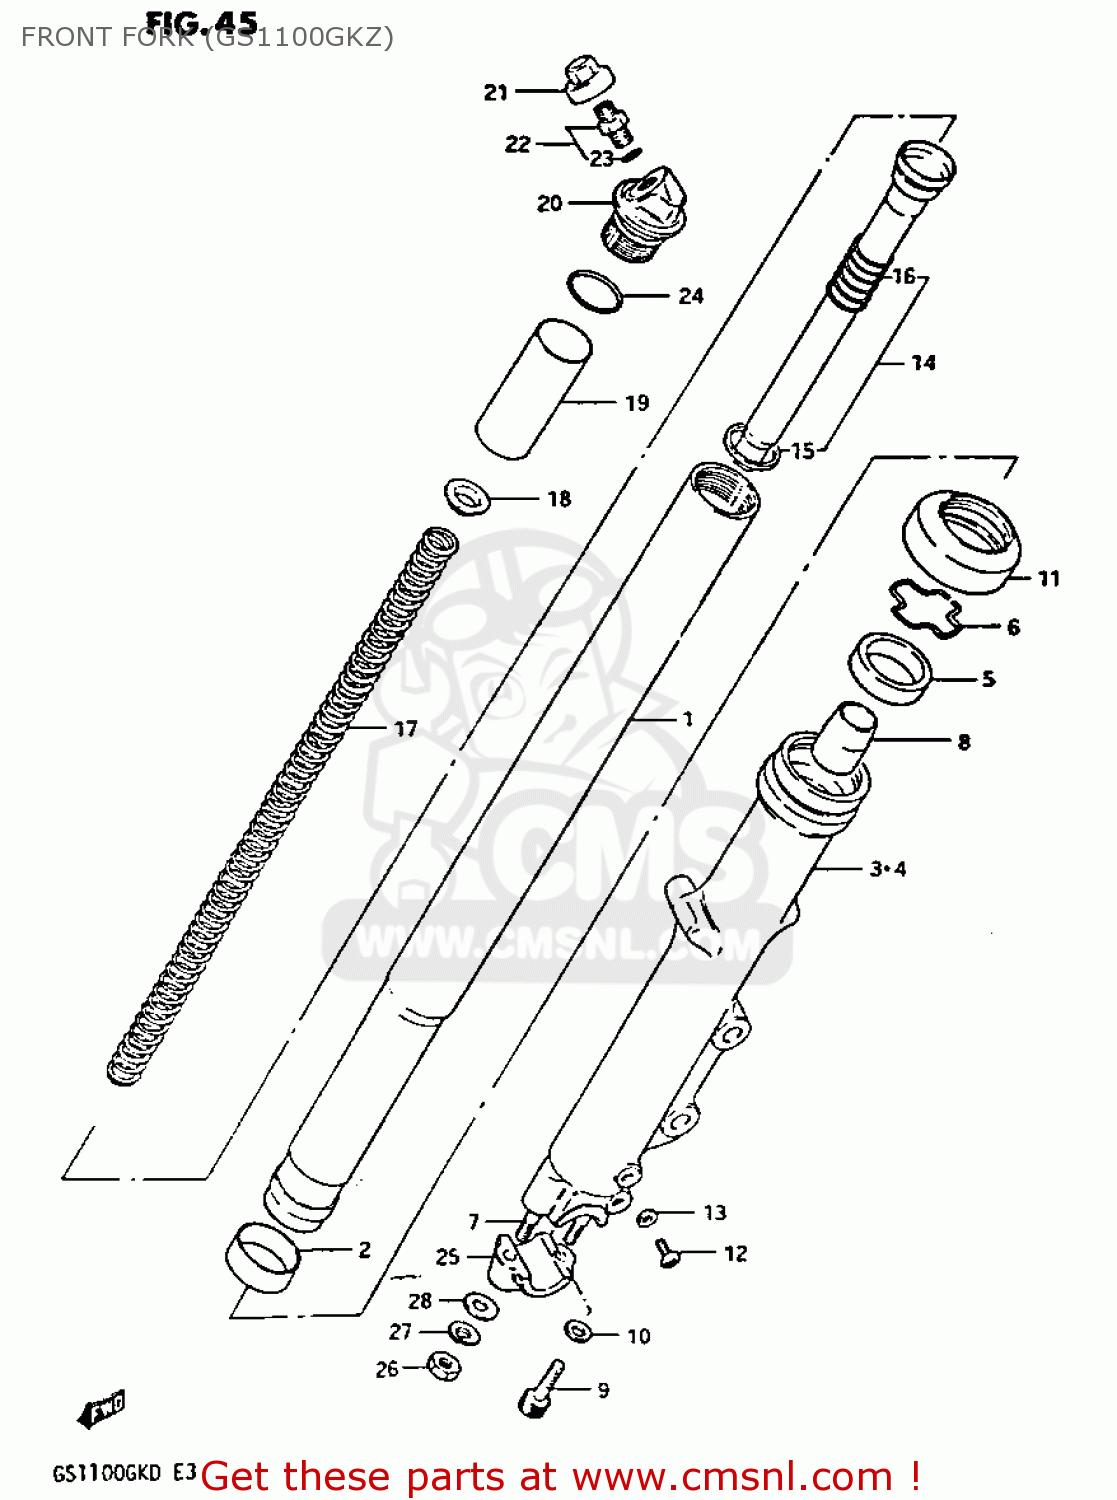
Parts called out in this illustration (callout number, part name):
1	TUBE,FORK,INNER
2	METAL,SLIDE FRONT FORK
3	TUBE,FORK,OUTER,RIGHT
4	TUBE,OUTER,LEFT
5	OIL SEAL,FRONT FORK
6	RING,OIL SEAL STOPPER
7	BOLT,STUD
8	PIECE,OIL LOCK
9	BOLT,CYLINDER
10	GASKET,CYLINDER (NAS)
11	SEAL,DUST
12	SCREW
13	GASKET,DRAIN,PLUG (NAS)
14	CYLINDER,FRONT FORK
15	RING,PISTON
16	SPRING,REBOUND
17	SPRING,FRONT FORK
18	GUIDE
19	SPACER,SPRING
20	CAP,FORK INNER TUBE
21	CAP,VALVE
22	VALVE
23	O RING
24	O RING
25	HOLDER,AXLE
26	NUT (8MM)
27	LOCK WASHER
28	WASHER
